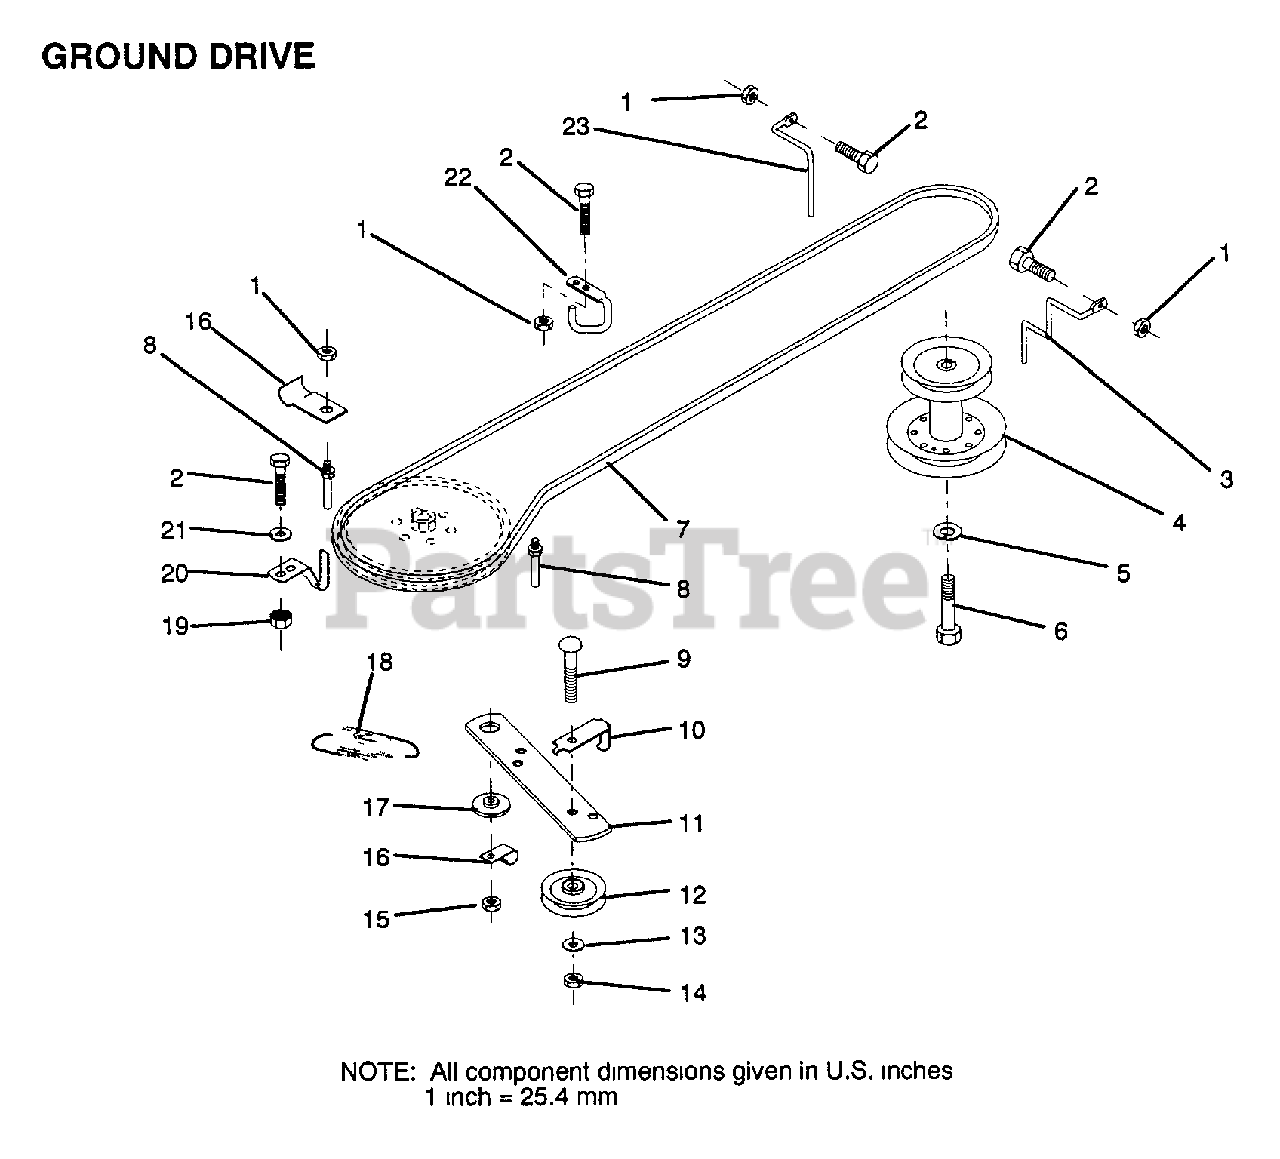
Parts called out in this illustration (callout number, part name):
2	BOLT
3	KEEPER ENG BEL LH
5	LOCKWASHER
6	BOLT
7	BELT
8	"KEEPER,DRIVE BELT"
9	BOLT
10	"KEEP,IDLER DR BEL"
12	PULLEY.IDLER.FLAT
13	WASHER
14	LOCKNUT
16	"CLIP,INSULATOR"
17	SPACER RETAINER
20	"KEEPER,DR BELT "
21	WASHER
22	"KEEPER,FRA DR BEL"
23	KEEPER ENG DR RH
